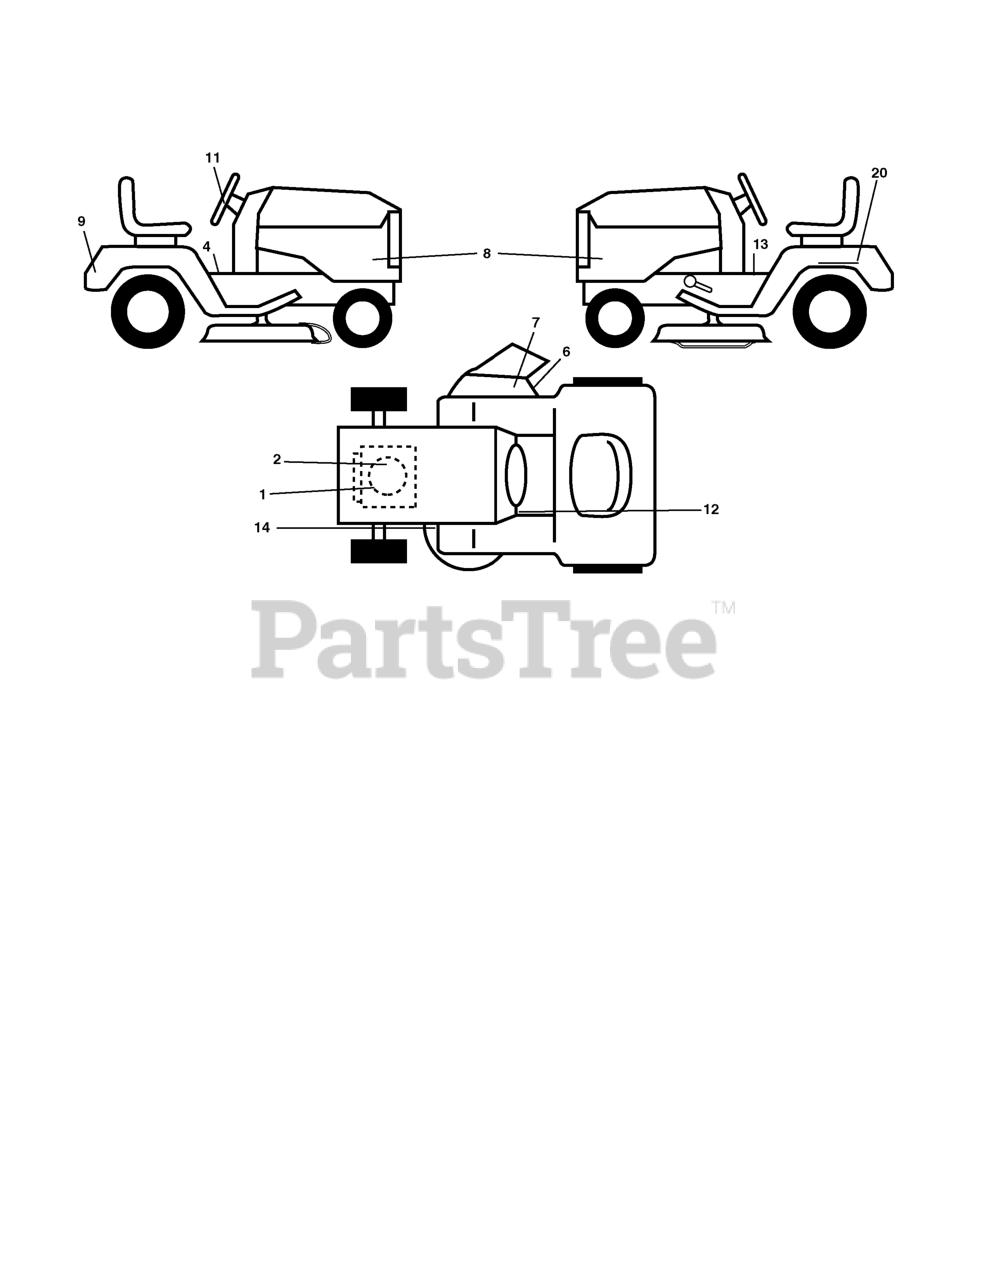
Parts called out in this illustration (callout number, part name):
1	DECAL, Warning
2	DECAL, Eng. H.P.
4	DECAL, Warning
6	DECAL, Warning, Keep Hand Away
7	DECAL, Cutfinger CE
8	DECAL, Side Panel
9	DECAL, Fender Logo
11	DECAL, Ins Strg Whl
12	DECAL, Brake Clutch
13	DECAL, Saddle Brake Park
14	DECAL, V-Belt Schematic
20	DECAL, Bat Dan/Psn
